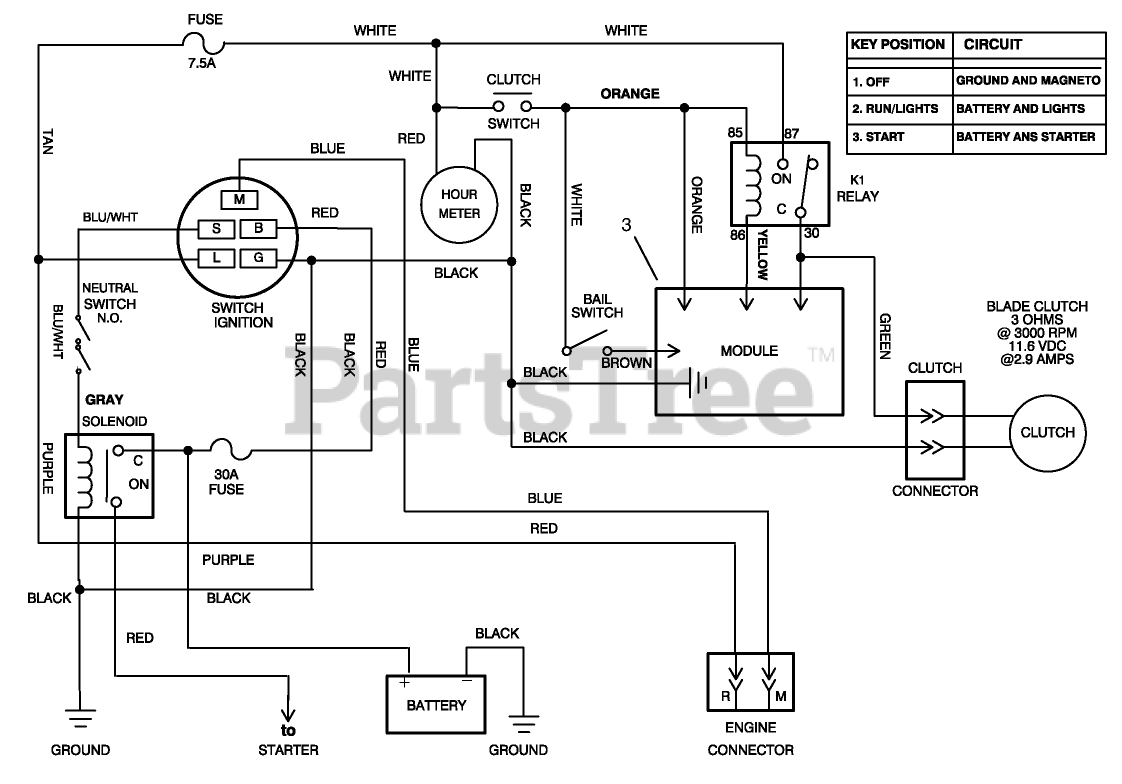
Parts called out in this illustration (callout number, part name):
1	WIRE HARNESS-18HP ELECT.
2	RELAY
3	Module
